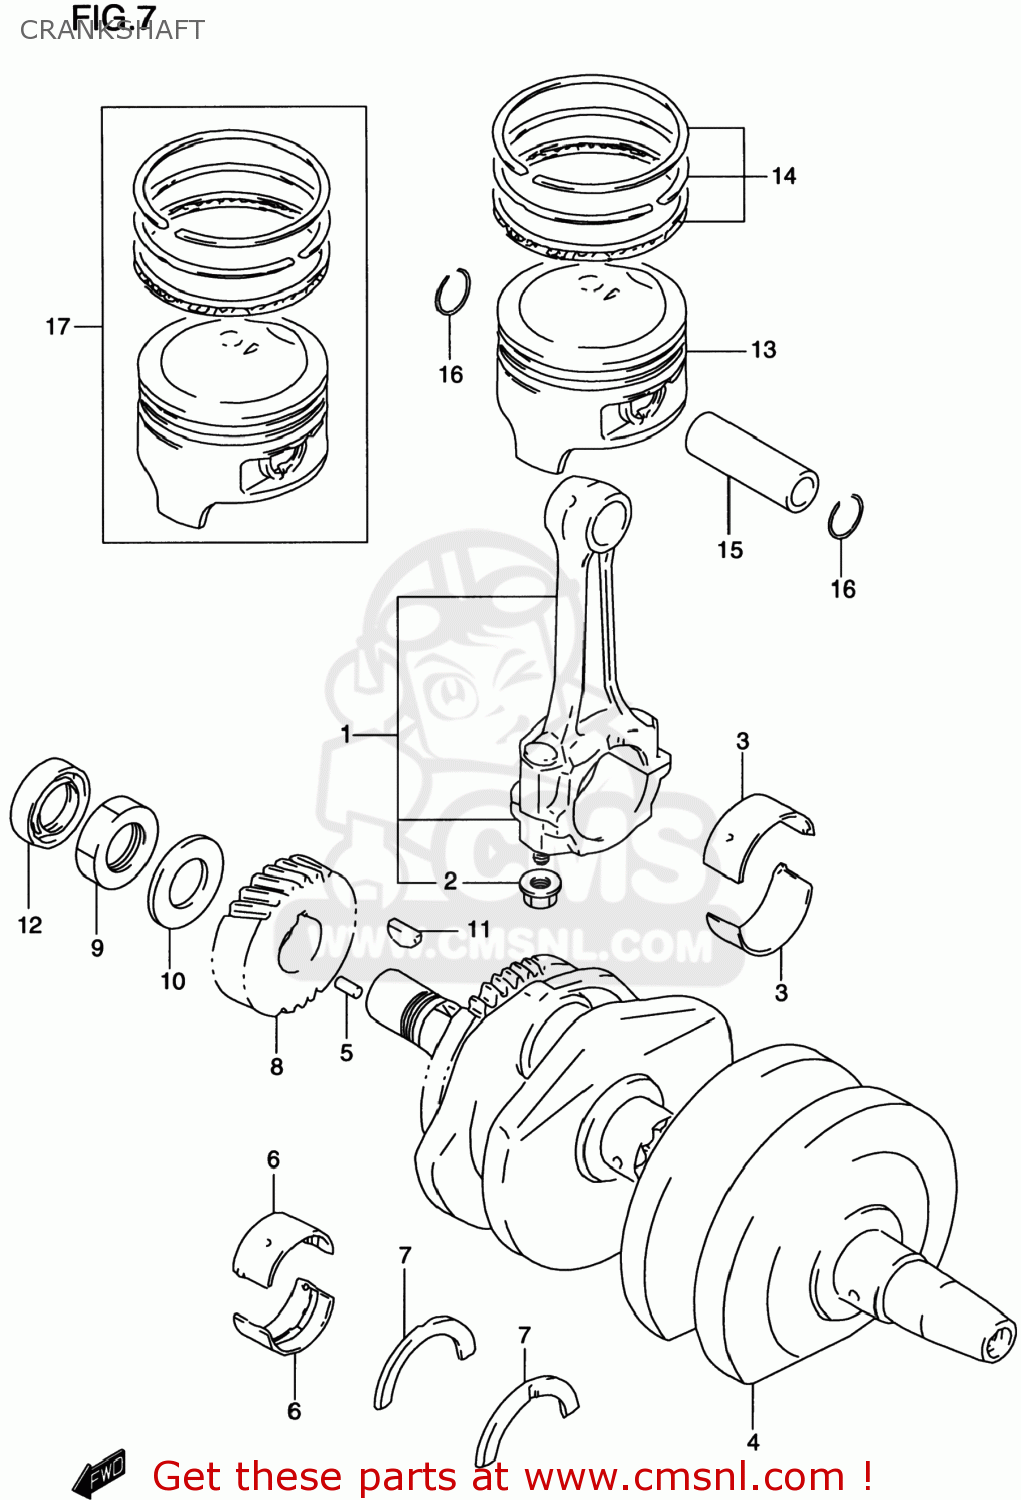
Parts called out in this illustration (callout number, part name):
1	ROD ASSEMBLY,CONNECTING
2	NUT
3	BEARING,CRANK PIN
4	CRANKSHAFT
5	PIN
6	BEARING,CRANKSHAFT(GREEN)
7	BEARING,CRANK THRUST
8	GEAR,PRIMARY DRIVE NO.28
9	NUT
10	WASHER
11	KEY
12	SEAL,OIL(22X40X8)
13	PISTON (74.00MM)
14	RING SET,PISTON
15	PIN,PISTON (18MM)
16	CIRCLIP
17	PISTON SET(OS:0.5)
